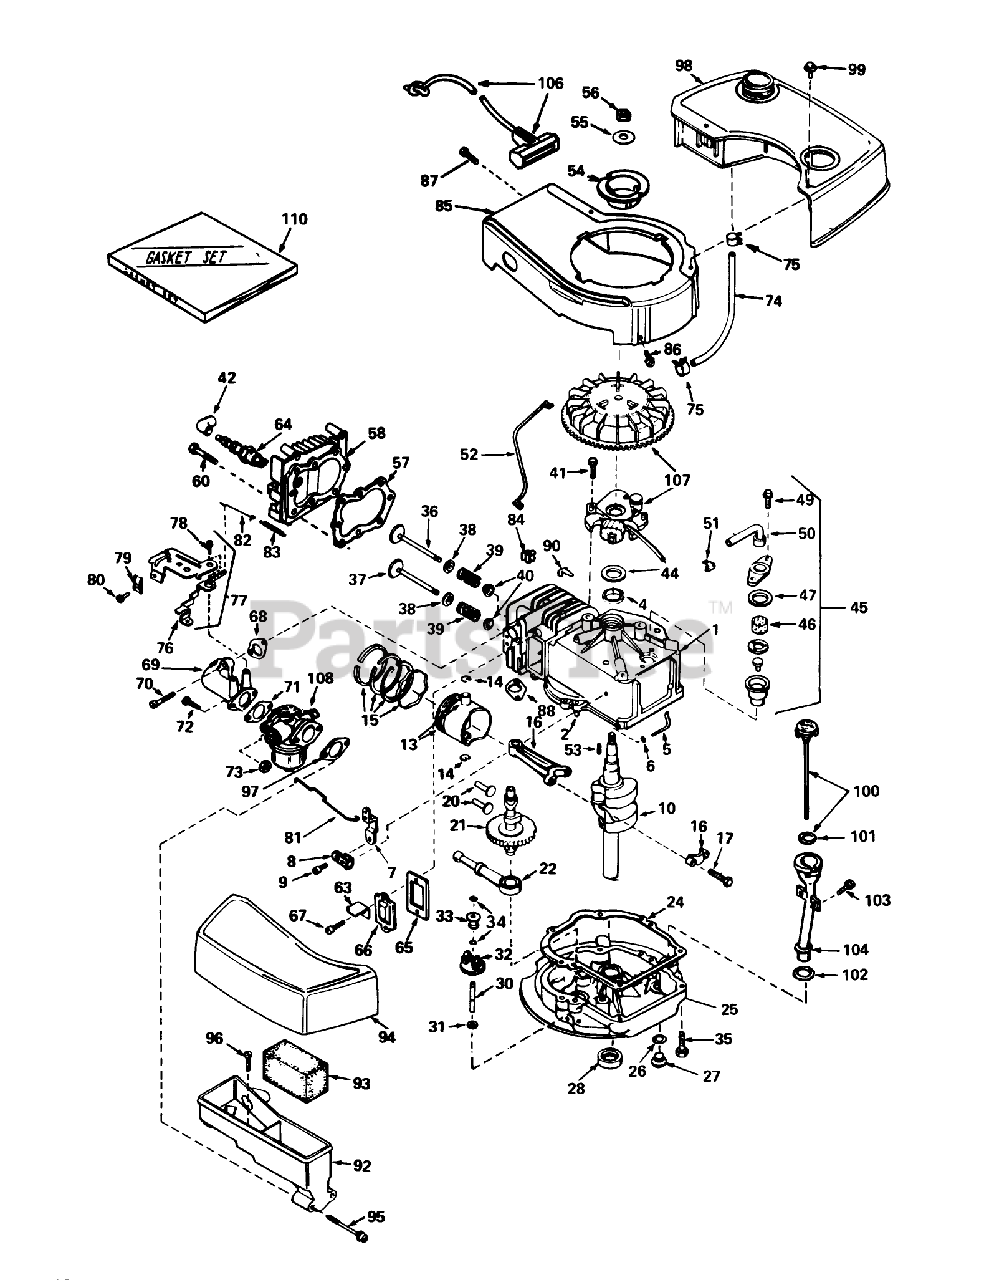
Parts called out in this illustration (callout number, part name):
1	Cylinder Assy. (Incl. Ref. #2, 4 105)
2	Pin-Dowel
4	OIL SEAL
5	Rod, Governor (Incl. No. 36)
6	Washer-Flat
7	Governor Lever
8	Clamp-Lever, Governor
9	Screw
10	Crankshaft
13	Piston, Pin Ring Assy. (Incl.Ref. #14 15)(Std.)
13	Piston, Pin Ring Assy. (Incl. #14 15)(.010 oversize)
13	Piston, Pin Ring Assy. (Incl.Ref. #14 15) (.020 oversize)
14	Ring-Retaining, Piston Pin
15	Ring Set Piston (Std.)
15	Ring Set Piston (.010 Oversize)
15	Ring Set Piston (.020 Oversize)
16	Rod Assy., Connecting (Incl. Ref. #17)
17	Bolt-Rod, Connecting
20	Lifter-Valve
21	Camshaft(Mech.Comp. Release)
22	Oil Pump ASM
24	Gasket, Mounting
25	Flange Assy., Mounting (Incl. Ref. #26thru 30)
26	Gasket-Oil Drain
27	Plug Oil Drain
28	Seal Oil
30	Shaft-Governor
31	Washer-Flat
32	Governor Gear ASM
33	Spool-Governor
34	Ring-Retaining
35	Screw (1/4-20 x 1-1/4)
36	Valve, Intake (Incl. Ref. #38, 39 40) (Std.)
36	Valve, Exhaust (1/32" Oversize) (Incl. Nos. 8, 9 10)
37	Valve, Exhaust (Standard) (Incl. Nos. 8, 9 10)
37	Valve, Exhaust (1/32" Oversize) (Incl. Nos. 8, 9 10)
38	Cap-Upper Valve Spring
39	Spring-Valve
40	Cap-Valve, Spring
41	Screw
42	Cover-Spark Plug
44	Gasket Stator
45	Breather Assy. (Incl. Ref. #46, 47, 49, 50 51 )
46	Element-Breather
47	Gasket-Breather
49	Screw, Hex Hd. w/Conical
50	Tube, Breaker
51	Clip, Breather
52	Wire, Ground
53	Key-Flywheel
54	Pulley Starter
55	Washer-Spring
56	Hex Nut
57	63573 GIL 42 SNWTHW
58	Head-Cylinder
60	Screw (5/16-18x1-1/2)
63	Retainer Clip
64	Plug, Spark (J17LM or equiv.)
64	Plug, Spark (Champion RCJ-8)
65	Gasket-Breather
66	Cover-Valve
67	Screw
68	Gasket, Intake
69	Pipe, Intake
70	Screw (1/4-20 x 1)
71	Gasket-Carburetor
73	Nut and Lock Washer (1/4-28)
74	Line-Fuel
75	Clamp-Line, Fuel
76	Lever Control
77	Control Assy., Speed (Incl. Nos, 76, 78 89)
78	Screw, Hex Washer Hd Shoulder Self-Tap
79	Conduit
80	Screw (10-32 x 3/8)
81	Link-Throttle
82	Link Governor Spring
83	Spring Governor
84	51004 GIL ROTARY TI
85	Housing Blower
86	Screw
87	Screw (10-24 x 9/16)
88	Gasket Exhaust
90	Clip-Wire
92	Body Air Cleaner
93	Filer, Air
94	Cove, Air Cleaner
95	Screw Fil Hd.
96	Screw, Hex Hd.
97	Gasket-Air Cleaner
98	Tank, Fuel
99	Screw (10-32 x 35/64)
100	Dipstick, Oil (Incl. Ref. #101)(Twist Lock)
101	O-Ring
102	Gasket
103	Screw (10-32 x 1/2)
104	Tube-Oil Fill
106	Rope Assy., Starter
107	Magneto
108	Carburetor (Incl. Ref. #71 )
110	53024/VAR.16HP O/P
